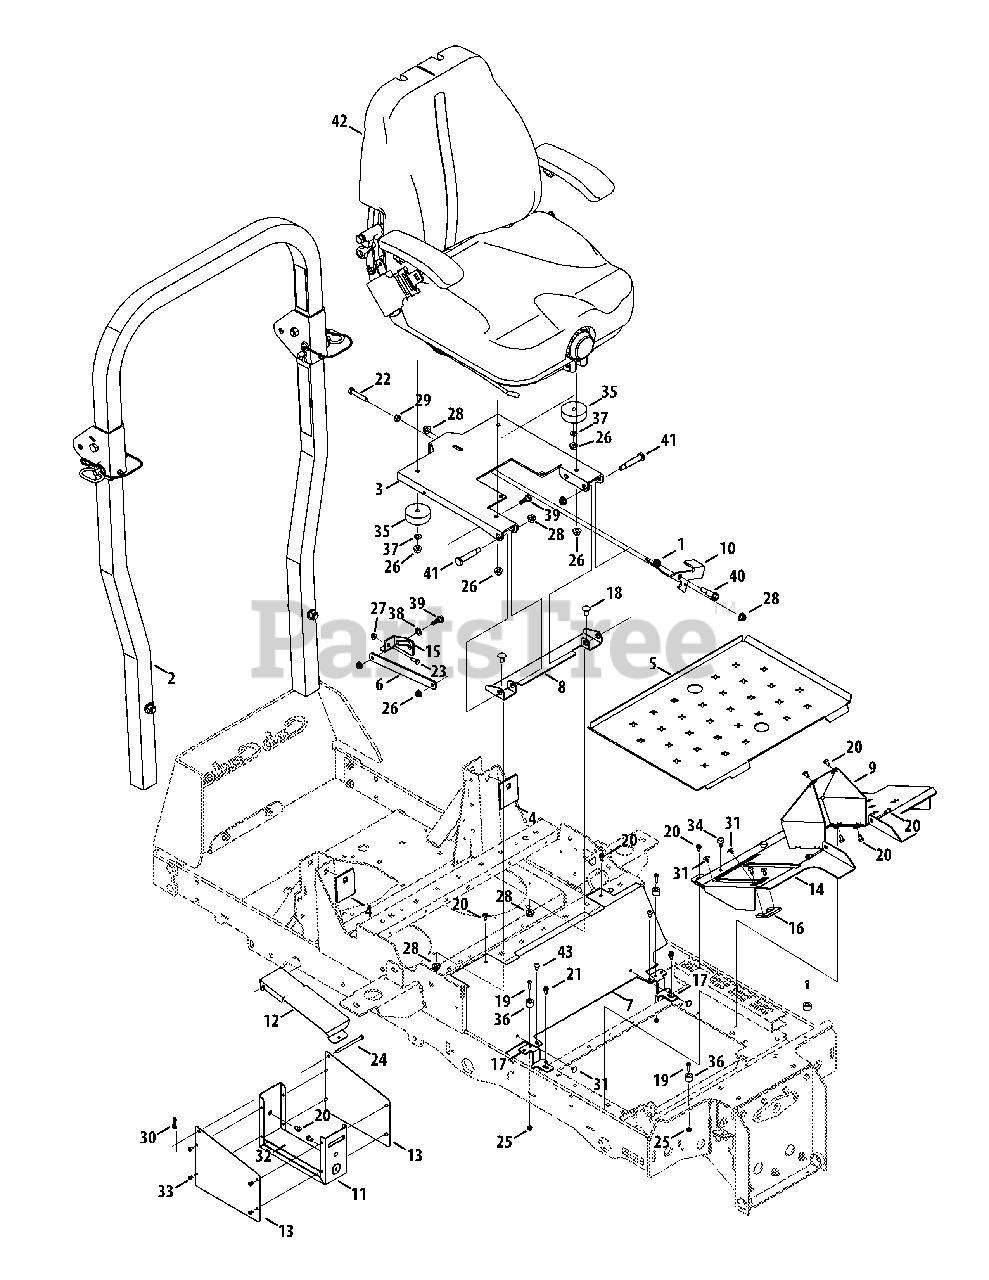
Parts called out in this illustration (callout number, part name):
1	Torsion Spring, .725 x 1.0 x .09
2	Folding ROPS Assembly
3	Seat Mounting Bracket
4	Deck Reinforcement Plate
6	Seat Lockout Bracket
7	Floor Panel Tray
8	Seat Mounting Bracket
10	Seat Lever Latch
12	Storage Box Lid
13	Storage Box Side Panel
15	Seat Lockout Mount
16	Stop Pedal Bracket
17	Frame Bracket, LH
18	Carriage Bolt, 3/8-16 x .75
19	Socket Head Screw, 10-24 x .75
20	Screw, 1/4-20 x .5
21	Hex Flange Screw, 1/4-20 x .500
22	Hex Cap Screw, 3/8-16 x 2.50
23	Hex Cap Screw, 1/4-20 x .75
24	Clevis Pin, .25 x 3.5
25	Nut, #10-24, Hexlock
26	Nut, 5/16-18, Flangelock
27	Nut, 1/4-20, Flangelock
28	Nut, 3/8-16, Flangelock
29	Nut, 3/8-16, Hex
30	Cotter Pin, Bow Tie
31	Clip, .250 Dia. x .500
32	Adhesive Pad
33	Rivet, 3/16 x .325
34	Bumper, .62 Dia. x .3
35	Rubber Bumper, 2.5 x 1.0
36	Rubber Bumper, .75 x .500
37	Washer, .344 x .688 x .065
38	Washer, .469 x .750 x .06
39	Shoulder Screw, .437 x .268, 5/16-18
40	Shoulder Bolt, .50 x .925, 3/8-16
41	Shoulder Bolt, .500 x 2.23, 3/8-16
43	Screw 1/4-20 x 3.75
